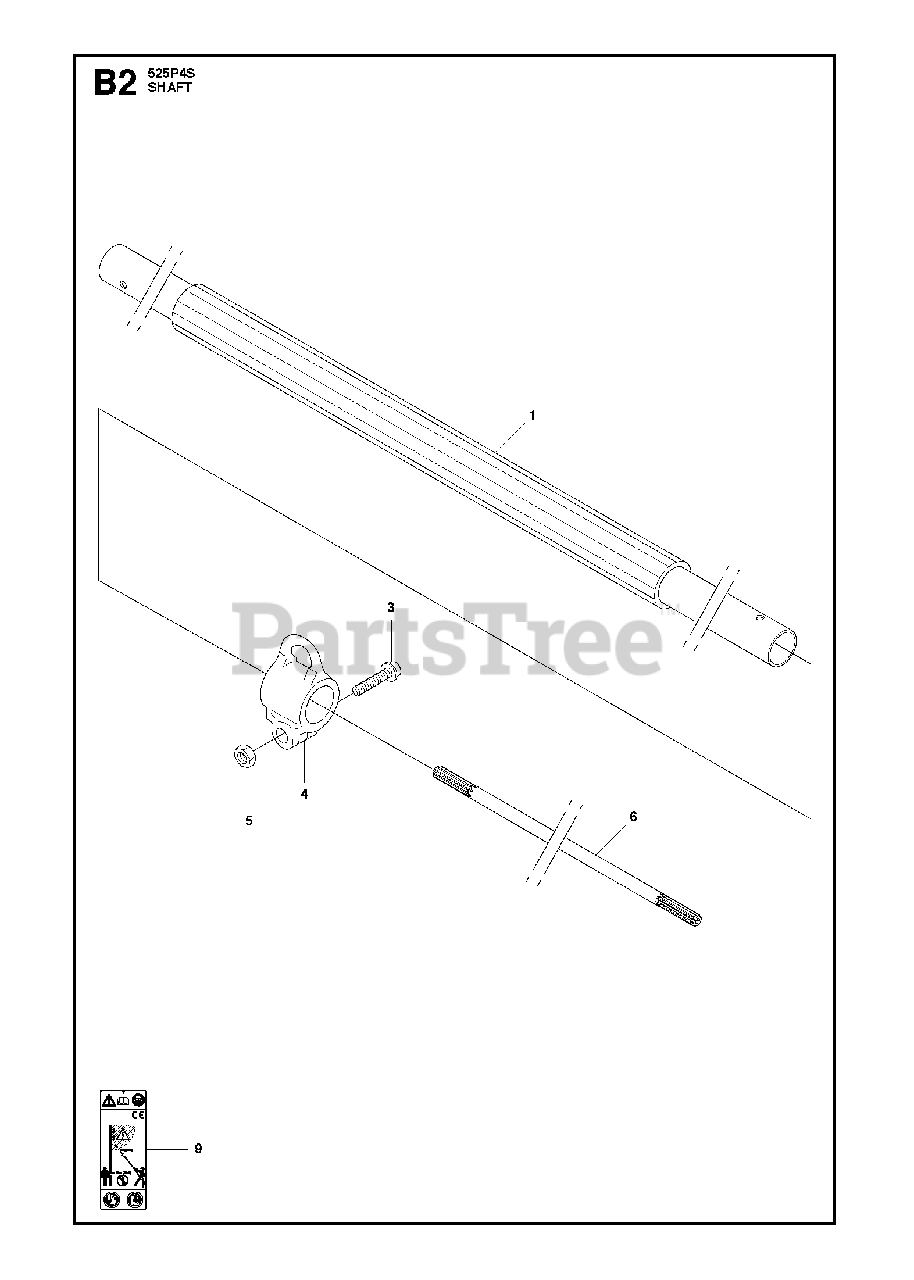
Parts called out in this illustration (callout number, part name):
1	TUBE
4	HARNESS HOLDER
6	DRIVESHAFT
9	DECAL WARNING SPARK ARRESTOR
